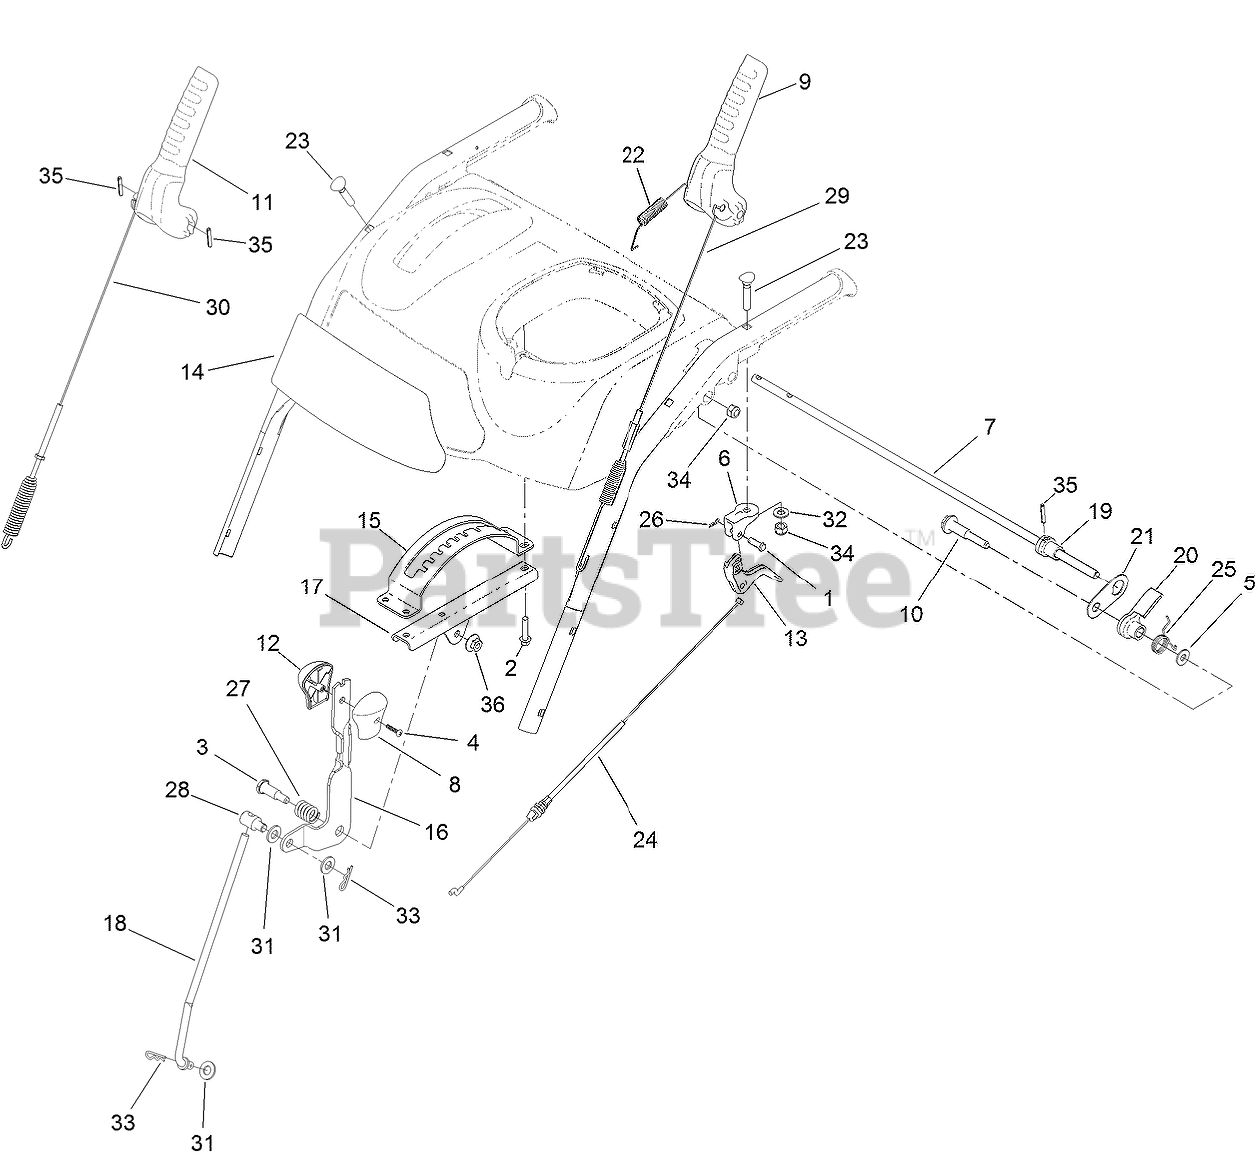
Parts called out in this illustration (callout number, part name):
1	PIN-CLEVIS
2	SCREW-PLASTITE, HWH
3	SCREW-SHOULDER, HH
4	SCREW-PPH
5	WASHER-FLAT
6	MOUNT-CLUTCH, LEVER
7	ROD-LOCKOUT
8	KNOB-SHIFT, LH
9	LEVER-TRACTION
10	SCREW-SHOULDER
11	LEVER-AUGER
12	KNOB-SHIFT, RH
13	LEVER-CLUTCH
14	DECAL-CONTROL PANEL
15	GUIDE-SELECTOR, SPEED
16	SELECTOR-SPEED
17	BRACKET-SELECTOR, SPEED
18	ROD-SHIFT
19	CAM-LOCKOUT
20	LATCH-LOCKOUT
21	LINK-LOCKOUT
22	SPRING-TENSION
23	SCREW-HANDLE
24	CABLE-CLUTCH
25	SPRING-TORSION
26	PIN-HAIR
27	SPRING-COMPRESSION
28	TRUNNION-ROD
29	CABLE-TRACTION
30	CABLE-AUGER
31	WASHER-FLAT
32	WASHER-PLAIN
33	PIN-HAIR
34	NUT-HEX
35	PIN-SPRING
36	NUT-HEX FLG
